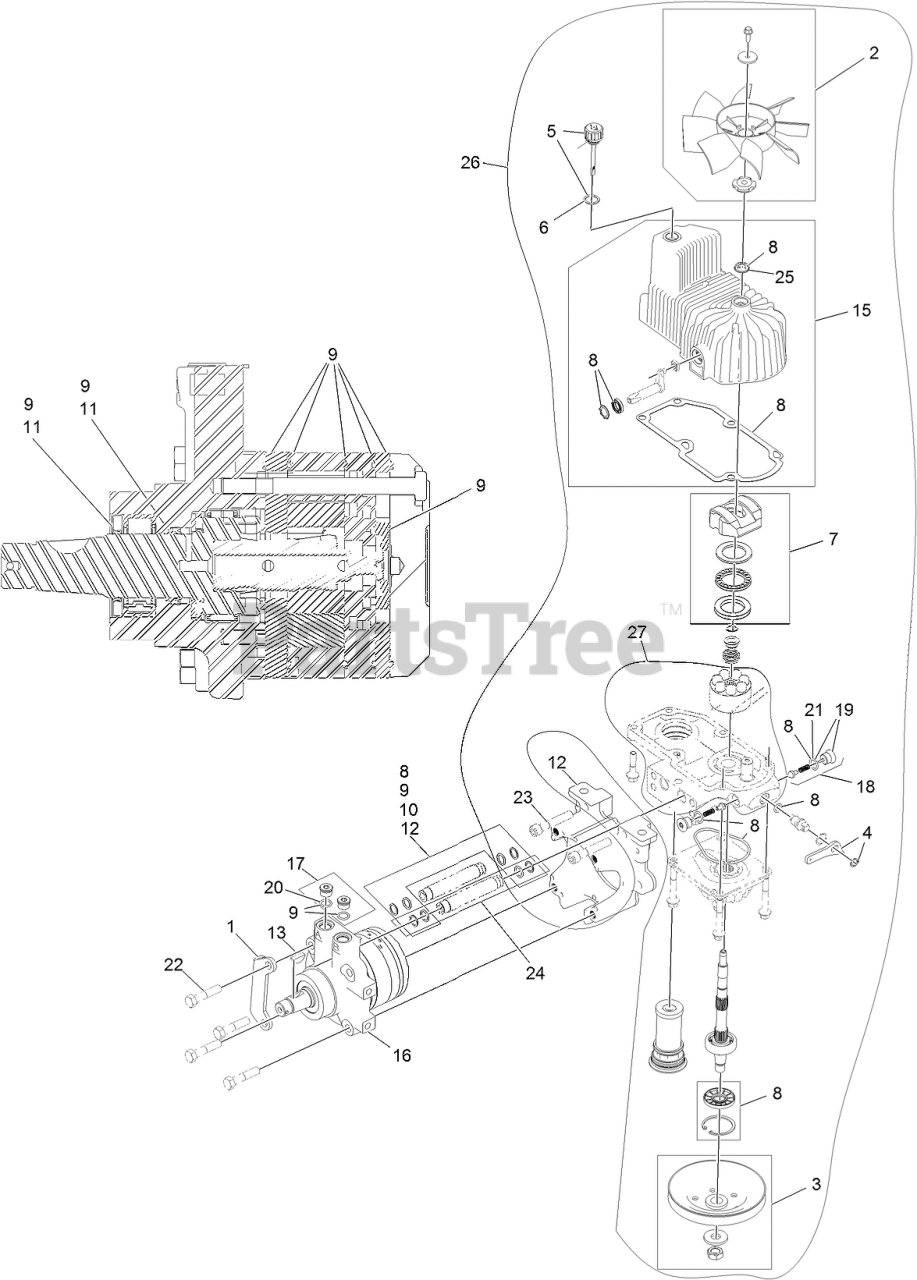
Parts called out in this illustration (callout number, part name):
1	MOUNT-SHOE, HORSE
2	FAN KIT
3	PULLEY KIT
4	HANDLE-BYPASS VALVE, HYDRO
5	DIPSTICK-HYDRO W/GASKET
6	GASKET-DIPSTICK, HYDRO
7	SWASH BLOCK KIT
8	PUMP SEAL KIT
9	MOTOR SEAL KIT
10	TUBE SEAL KIT
11	OUTPUT SHAFT SEAL KIT
12	NOSE CUP-UHT
13	KEY-WOODRUFF
15	HOUSING-HYDRO, RH
16	MOTOR-HYDRAULIC RH 240CC
17	MAGNETIC PLUGS SERVICE KIT
18	CHECK VALVE ASM
19	PLUG-CHECK (W/O-RING)
21	O-RING-CHECK VALVE
22	SCREW HH
23	SCREW-HSH
24	HYDRAULIC TUBE KIT
25	SEAL-FAN DRIVE
26	Kit, Pump Section 12Cc RH
27	FLOW TEST KIT
